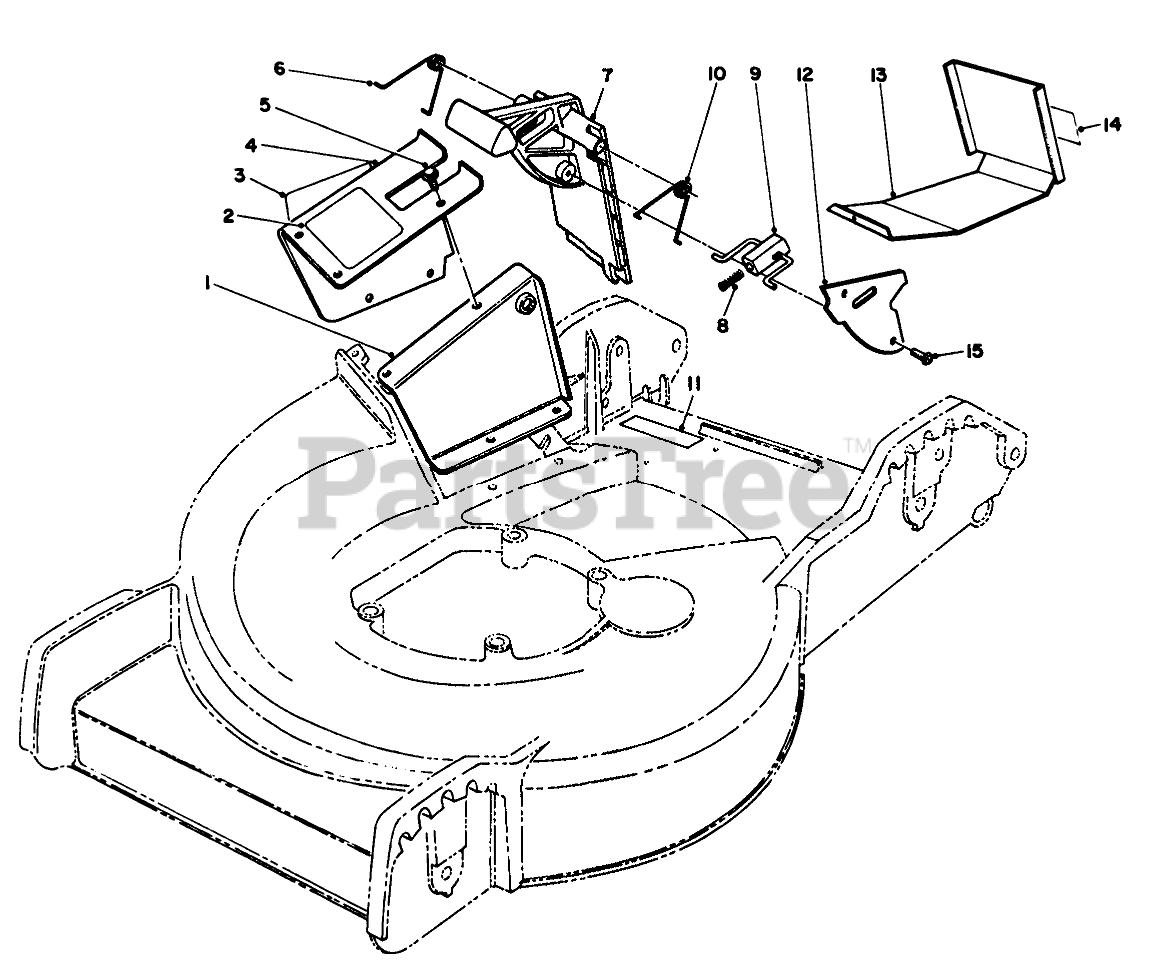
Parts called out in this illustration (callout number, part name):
1	Tunnel-Inner
2	DECAL - CAUTION DOOR
3	DECAL-DANGER
4	Tunnel-Outer (Incl. Ref. #2 & 3)
5	SCREW-HWH
6	SPRING-DOOR, RH
8	SPRING-COMPRESSION, LATCH
9	LATCH-DOOR
10	LH DOOR SPRING
11	DECAL - CAUTION
12	DOOR COVER
13	Discharge Plug Assembly (Incl. Ref. #14)
14	DECAL - WARNING
